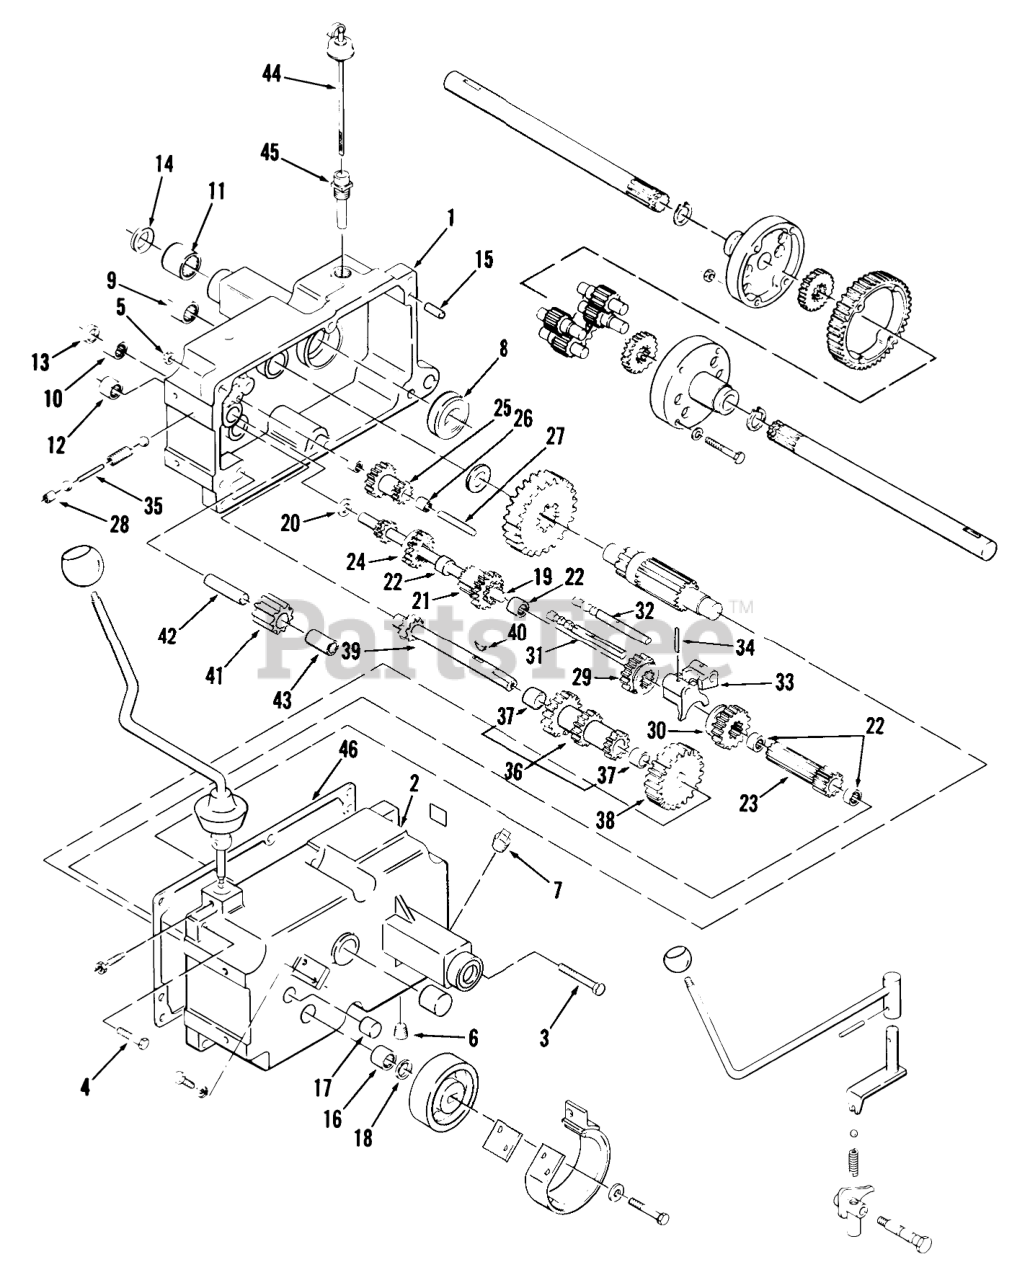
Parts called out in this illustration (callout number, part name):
1	Case-R.H.
2	Case LH.
3	HHCS
4	Bolt
5	Nut
6	PLUG 1/4 PIPE ALLEN
7	Plug
8	BALL BRG 1 1/2 I.D.
9	BEARING-NEEDLE
10	BEARING-NEEDLE
11	BEARING-NEEDLE
12	BEARING-NEEDLE
13	SEAL-OIL
14	OIL SEAL
15	PIN-DOWEL
16	BEARING-NEEDLE
17	Bearing Needle
18	SEAL-OIL
19	SHAFT-INPUT
20	WASHER-THR
21	GEAR
22	BEARING-NEEDLE
23	GEAR
24	GEAR-SLIDING
25	Gear
26	BEARING-NEEDLE
27	GEAR-SHAFT REDUCTION
28	CUP-PLUG
29	GEAR-HI AND 2ND
30	GEAR-LOW AND REVERSE
31	RAIL-SHIFT
32	RAIL-REAR SHIFT
33	FORK-SHIFT
34	PIN-ROLL
35	PIN-SHIFT
36	GEAR-CLUSTER
37	BUSHING-BRONZE
38	GEAR-CLUSTER SHAFT
39	Cluster Shaft
40	KEY-WOODRUFF
41	GEAR/BUSHING ASM-REVERSE IDLER
42	PIN-DIFFERENTIAL
43	BUSHING
44	Dipstick
44	ASSY-DIPSTICK
45	NIPPLE-FILL, TRANSMISSION
45	NIPPLE-TRANS FILL
46	GASKET-TRANSMISSION
